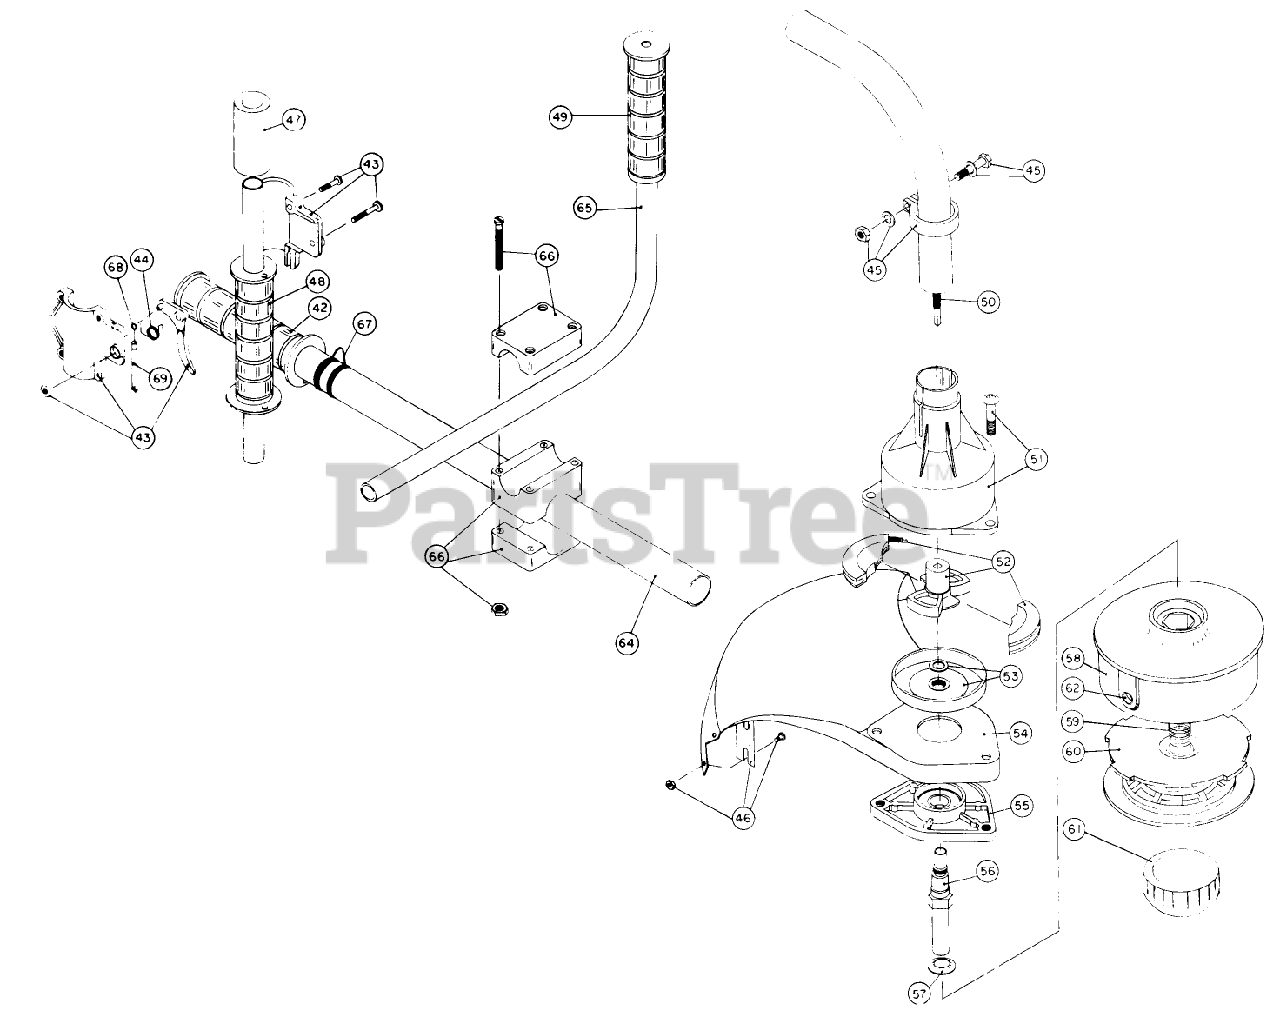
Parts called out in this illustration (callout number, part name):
44	THROTTLE TRIGGER SPRING
46	BLADE ASM
51	CLUTCH HSG ASM
71	Monoflail cuttig line 1 lb.
